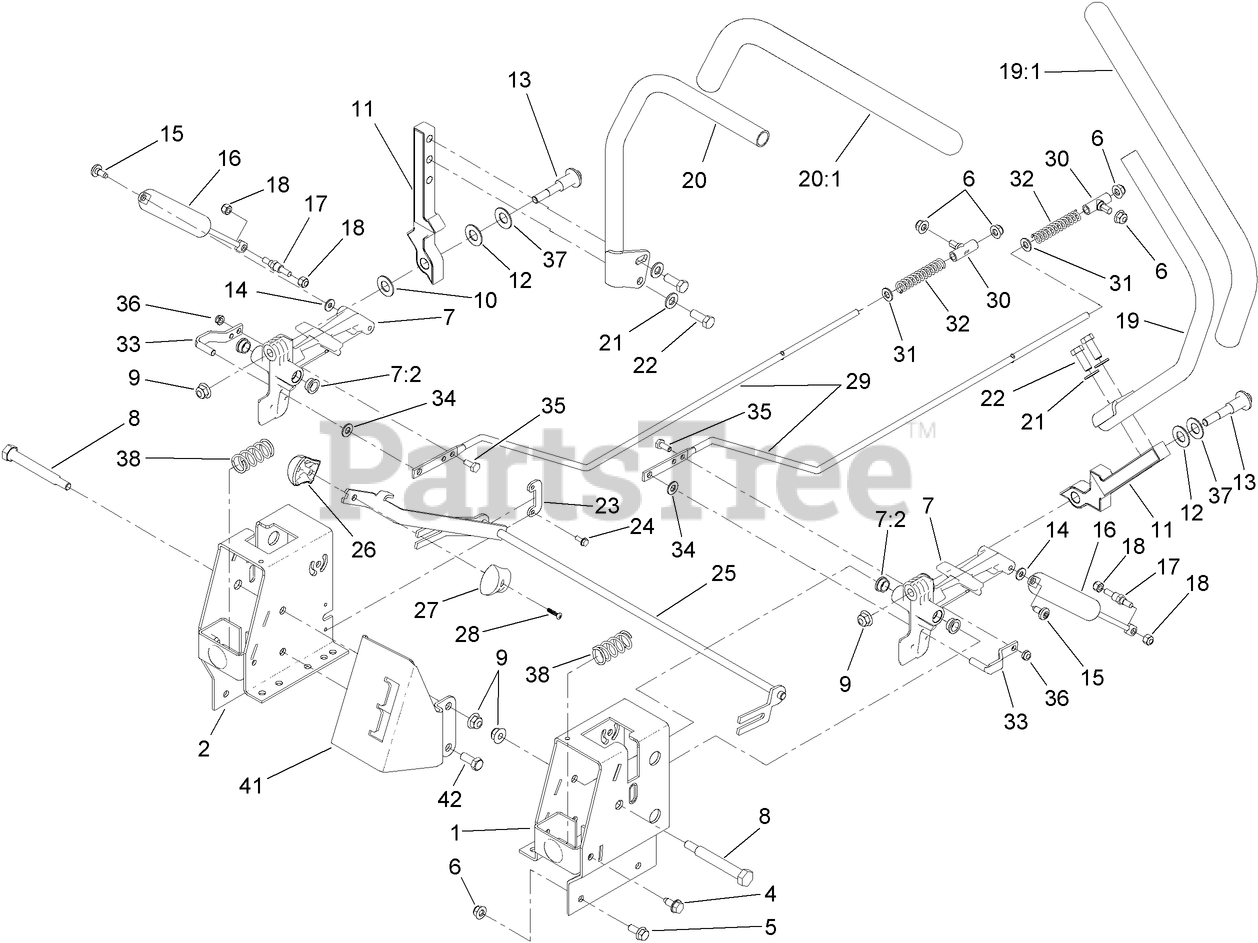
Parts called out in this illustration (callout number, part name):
1	BOX-CONTROL, LH
2	BOX-CONTROL, RH
4	SCREW-HWHTF
5	SCREW-HHF
6	NUT-HF, NI
7	ACTUATOR ARM ASM
7:2	BUSHING-FLANGE
8	BOLT-PIVOT
9	NUT-HF, NI
10	WASHER-NYLON
11	ARM-CONTROL
12	WASHER
13	BOLT-PIVOT
14	WASHER
15	SCREW-SHOULDER
16	DAMPER
17	STUD-DAMPER
18	NUT-LOCK, NI
19	HANDLE-CONTROL, LH
20	HANDLE-CONTROL, RH
21	WASHER-FLAT
22	SCREW-HH
23	RETAINER
24	SCREW-TAPTITE
25	CONTROL-SPEED
26	KNOB-RH
27	KNOB-LH
28	SCREW-PPH
29	ROD-HYDRO
30	MOUNT-ROD, HYDRO
31	WASHER-PLAIN
32	SPRING-RETURN, NEUTRAL
33	PIN-ROD, HYDRO
34	SPACER-NYLON
35	SCREW-HH
36	NUT-LOCK, NI
37	WASHER-BELLEVILLE
38	SPRING-RETURN
41	GATE-CONTROL, SPEED
42	SCREW-HH
